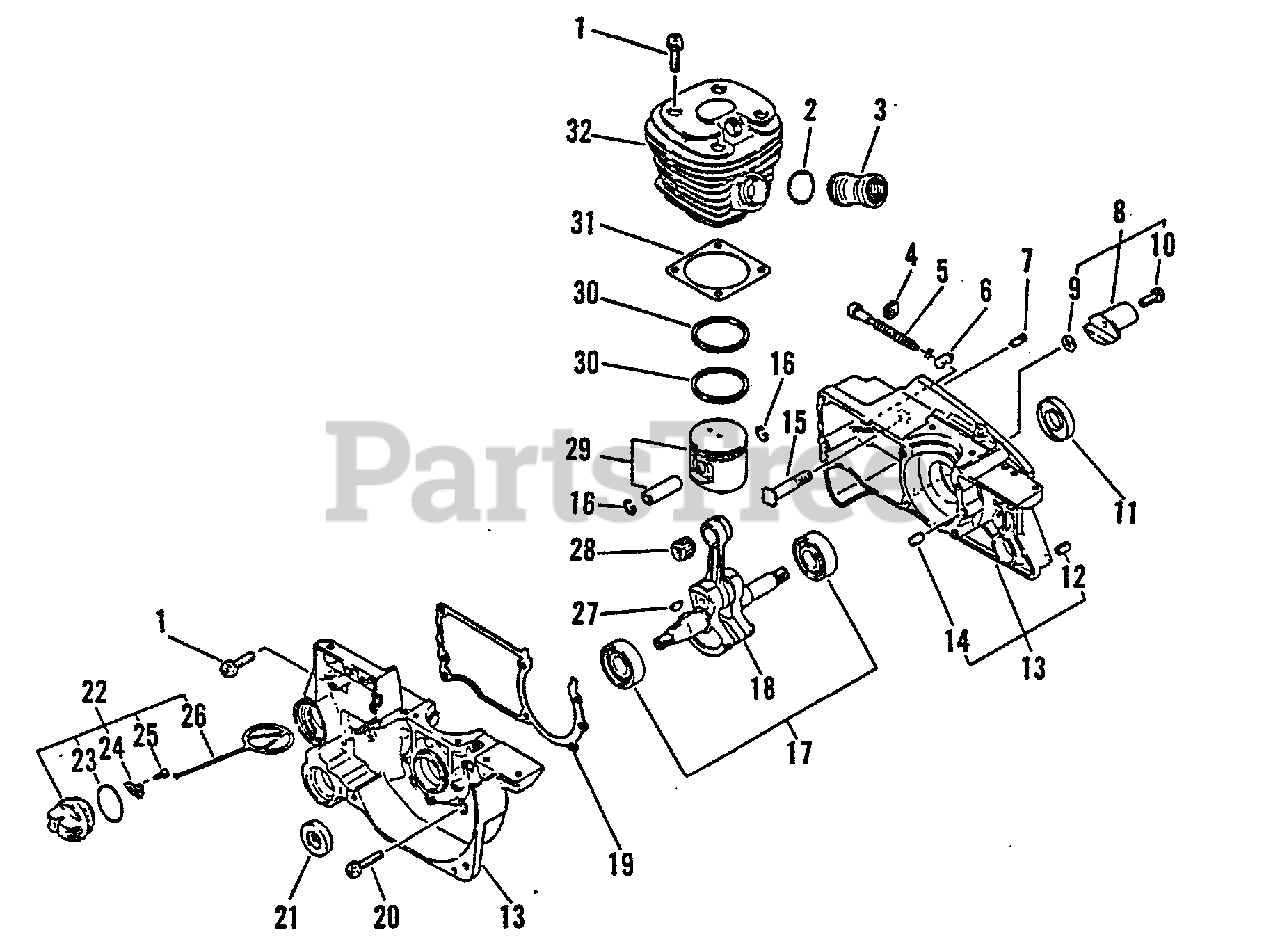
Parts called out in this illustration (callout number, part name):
1	SCREW - 5X20
2	BAND
3	ADAPTOR, INTAKE
5	SCREW, TENSIONER
6	TENSIONER, CHAIN
7	VENT, TANK
8	CHAIN CATCHER KIT
9	WASHER - 5
10	SCREW - 5X18
11	SEAL, OIL
12	PIN - SPRING -- 5X10
13	CRANKCASE KIT
14	PIN - LOCATING
15	STUD, GUIDE BAR
16	RING, RETAINING - 8
17	BEARING SET
18	CRANKSHAFT ASSY
19	GASKET, CRANKCASE
20	SCREW - 5X30
21	SEAL, OIL
22	CAP ASSY
23	O-RING - 25
24	RETAINER
25	SCREW - 3X8
26	CONNECTOR, CAP
28	BEARING, NEEDLE
29	PISTON KIT
30	RING, PISTON
31	GASKET, CYLINDER
32	CYLINDER
